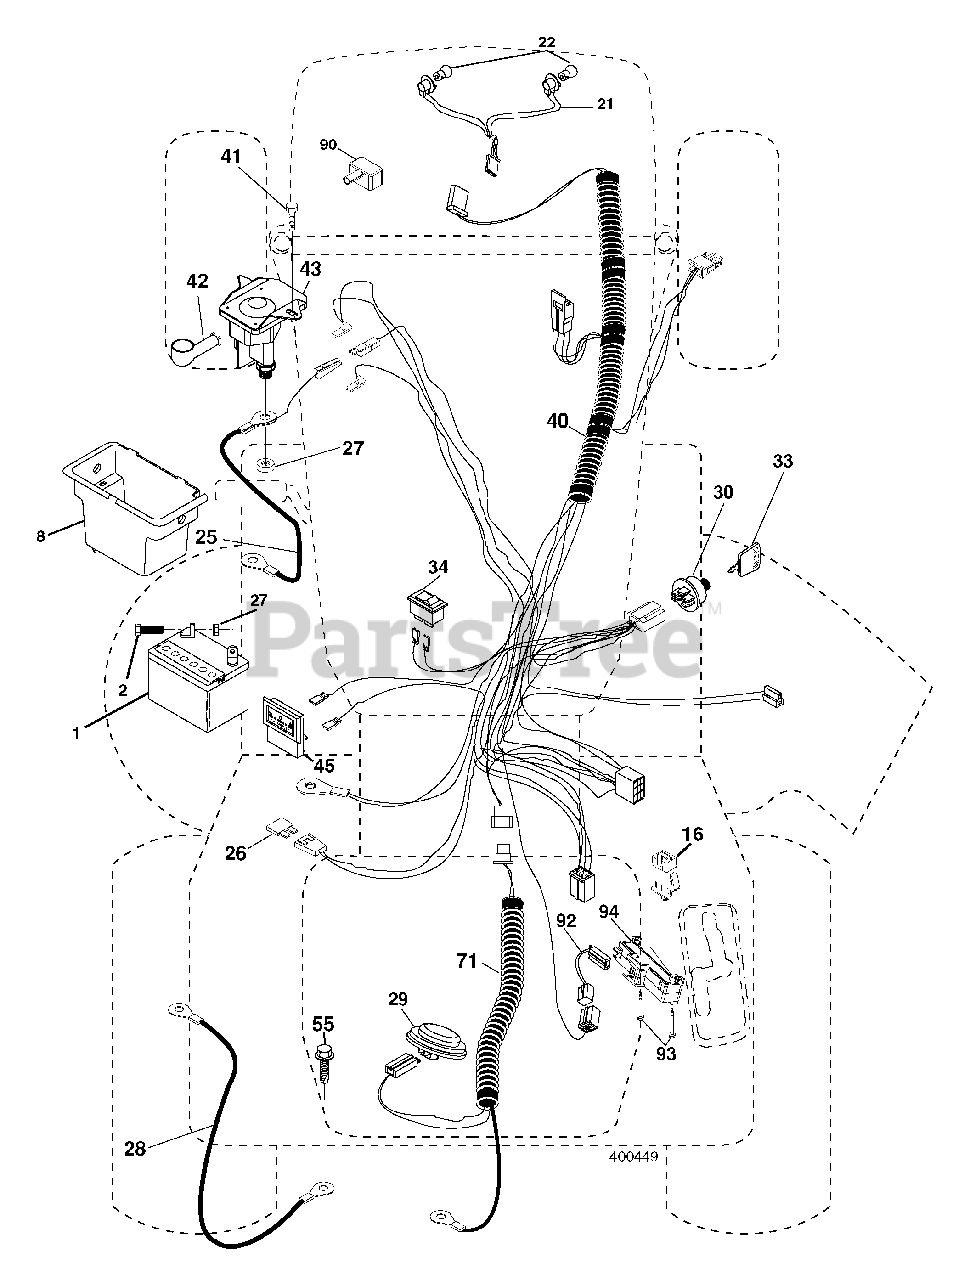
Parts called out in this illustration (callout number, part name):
1	Battery
2	Bolt Hex Head 1/4-20 x 3/4
8	Box Battery
16	Switch Interlock Push-In
21	Harness Socket Light W/4152J
22	Bulb Light
25	Cable Starter
26	Fuse
27	Nut Keps Hex 1/4-20 unc
28	Cable, Ground
29	Switch, Seat
30	Switch, Ign
33	Key, Ignition
34	Switch Light / Reset
40	Harness Ign.
41	Screw Thd Cut 1/4-20 x 1/2
42	Cover, Terminal
43	Solenoid
45	Ammeter
55	Screw Thdrol 5/16-18 x 3/4 TYTT
71	Harness Ign. Dash
90	Cover Terminal Battery
92	Harness Pigtail
93	Screw Plastite 10-14 x 2.0
94	Module Reverse ROS
